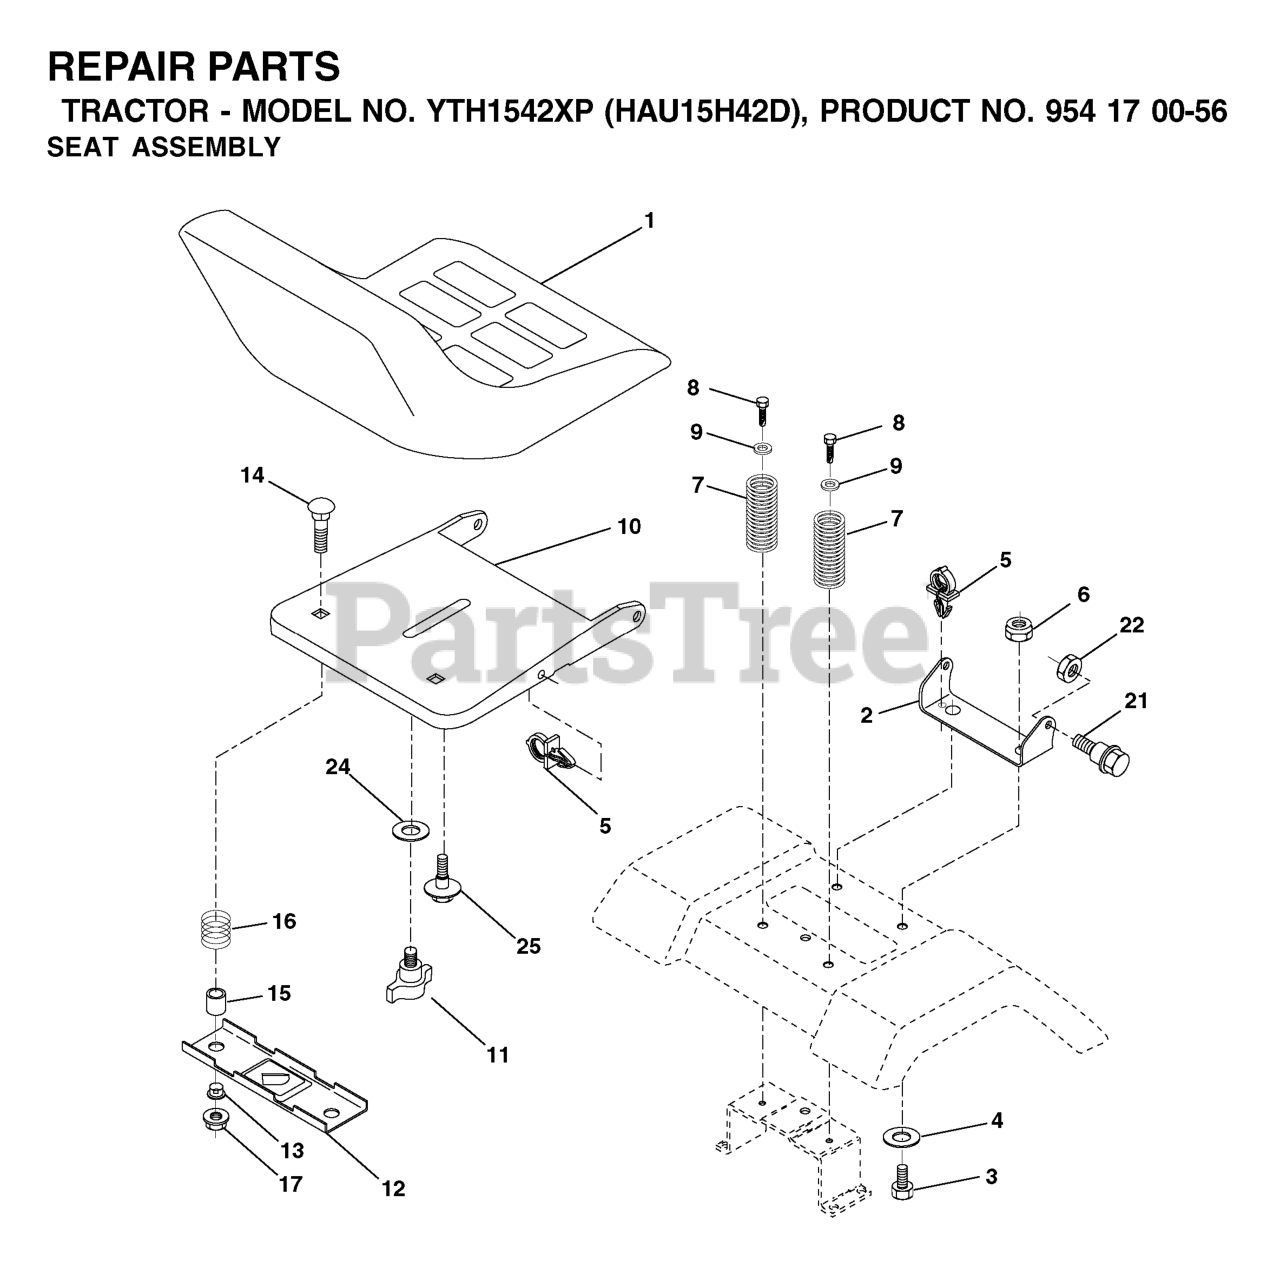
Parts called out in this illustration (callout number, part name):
1	SEAT, GRAY
2	SEAT PIVOT BRKT
3	BOLT, HEX 3/8-16X1
6	NUT
7	SPRING COMPRESSION
8	SCREW 3/8-16X1
9	WASHER
10	PAN SEAT
11	KNOB.SEAT.ADJ.WINGNUT
12	BRKT SWITCH
14	BOLT.ROUND.HEAD.SQUARE.NECK
15	SPACER SPLIT
16	SPRING COMPRESSED
17	NUT T
21	BOLT.SHOULDER.5/16-18
22	NUT.71038.31-18.HEX.NYLOCK
25	BOLT,SHOULD
